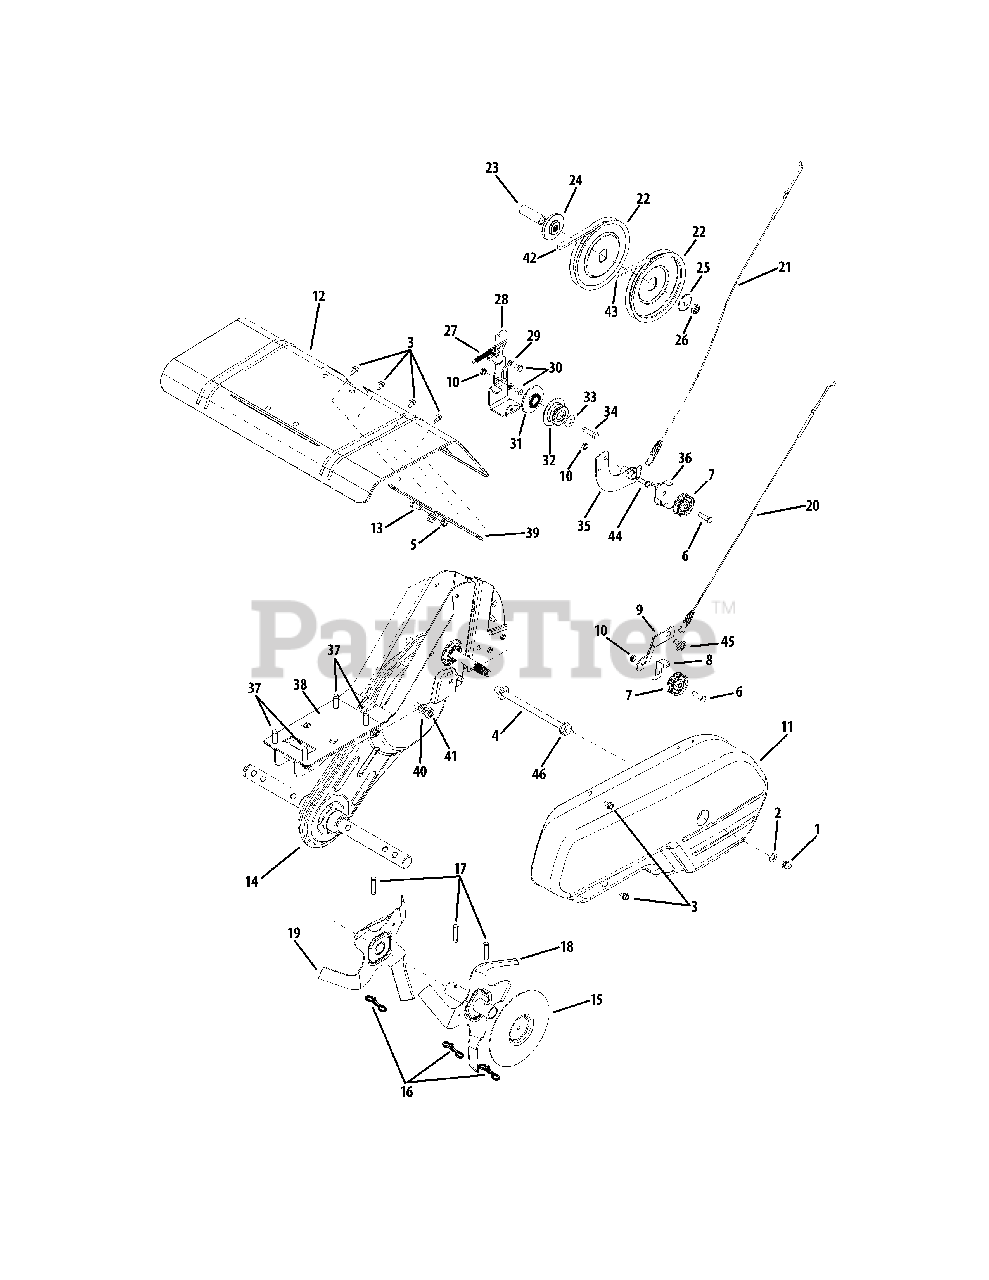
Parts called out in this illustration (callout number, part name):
1	Hex L-Stop Nut, 1/4-28
2	Flat Washer, 266" x .625"
3	Hex Washer TT-Tap Screw, 1/4-20 x .5"
4	Belt Cover Bolt
5	Hex Flange Top L-Nut, 5/16-18
6	Hex Head Screw, 3/8-16 x 1.25"
7	Flat Idler Pulley, 2.12"
8	Idler Belt Keeper
9	Idler Bracket
10	Hex Center Jam Nut, 3/8-16
13	Hex Head Cap Screw, 5/16-18 x .75"
14	Chain Case Assembly Complete
15	Outer Disc Plate Assembly
16	Cotter Pin, Bow Tie
17	Clevis Pin
18	Outer Tine Assembly, Left
18	Outer Tine Assembly, Right
19	Inner Tine Assembly, Left
19	Inner Tine Assembly, Right
20	Forward Clutch Cable
21	Reverse Clutch Cable
22	Flat Pulley, 6"
23	Spacer, .64" x 2.4"
24	Pulley Mounting Adapter
25	Bell Washer, 525" x 1.5"
26	Hex Jam Nut, 1/2-20
27	Return Spring
28	Reverse Bracket
29	Lock Washer, 5/16
30	Hex Bolt, 5/16-24 x .625"
31	Engine Inner Pulley
32	Reverse Engine Pulley
33	Bell Washer, .396" x 1/14"
34	Hex Bolt, 3/8-24 x 1.00"
35	Reverse Arm Assembly
36	Reverse Belt Keeper
37	Hex L-Washer TT-Tap, 3/8-16 x 1.25"
39	Tine Shield Bracket
40	L-Washer, 7/16"
41	Hex Nut, 7/16-20
42	Forward Drive Belt, 1/2 x 41.9"
43	Reverse Drive Belt, 3/8 x 45.68"
44	Shoulder Screw, .498 x 1.445
45	Shoulder Screw, .560 x.165
46	Flangelock Nut, 5/16 - 18
